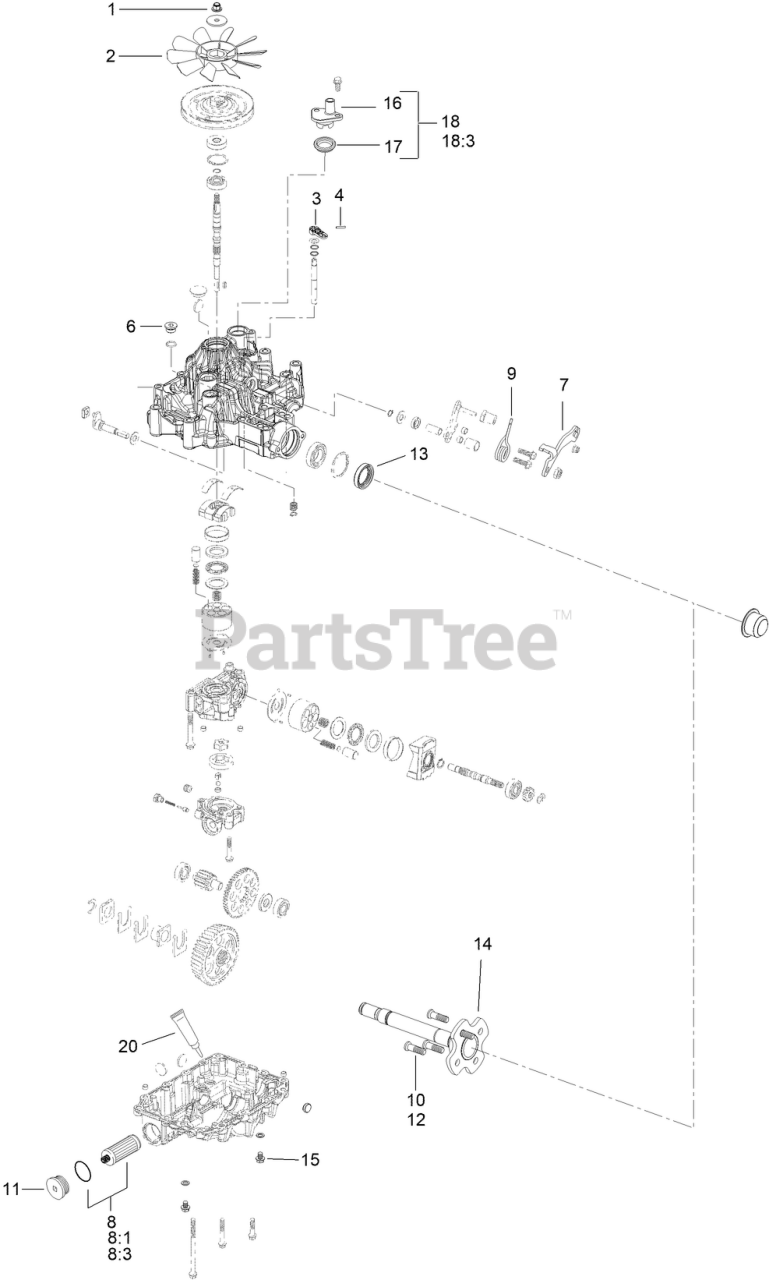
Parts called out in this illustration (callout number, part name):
1	NUT-LOCK
4	LEVER-BYPASS
6	CAP-OIL
7	LEVER-CONTROL, RH
8	2 TRANSMISSION FILTER KIT
8:3	SEALING WASHER
9	SPRING-TORSION
10	STUD-WHEEL
11	CAP-OIL FILTER
12	STUD-WHEEL
13	SEAL-AXLE, UA
15	DRAIN BOLT
16	EXPANSION FITTING
17	GROMMET SEAL, EXPANSION FITTING
18	EXPANSION FITTING - W/ SEAL
18:3	M8*20 FLANGE BOLT
20	KIT-SEAL, HYDRO
